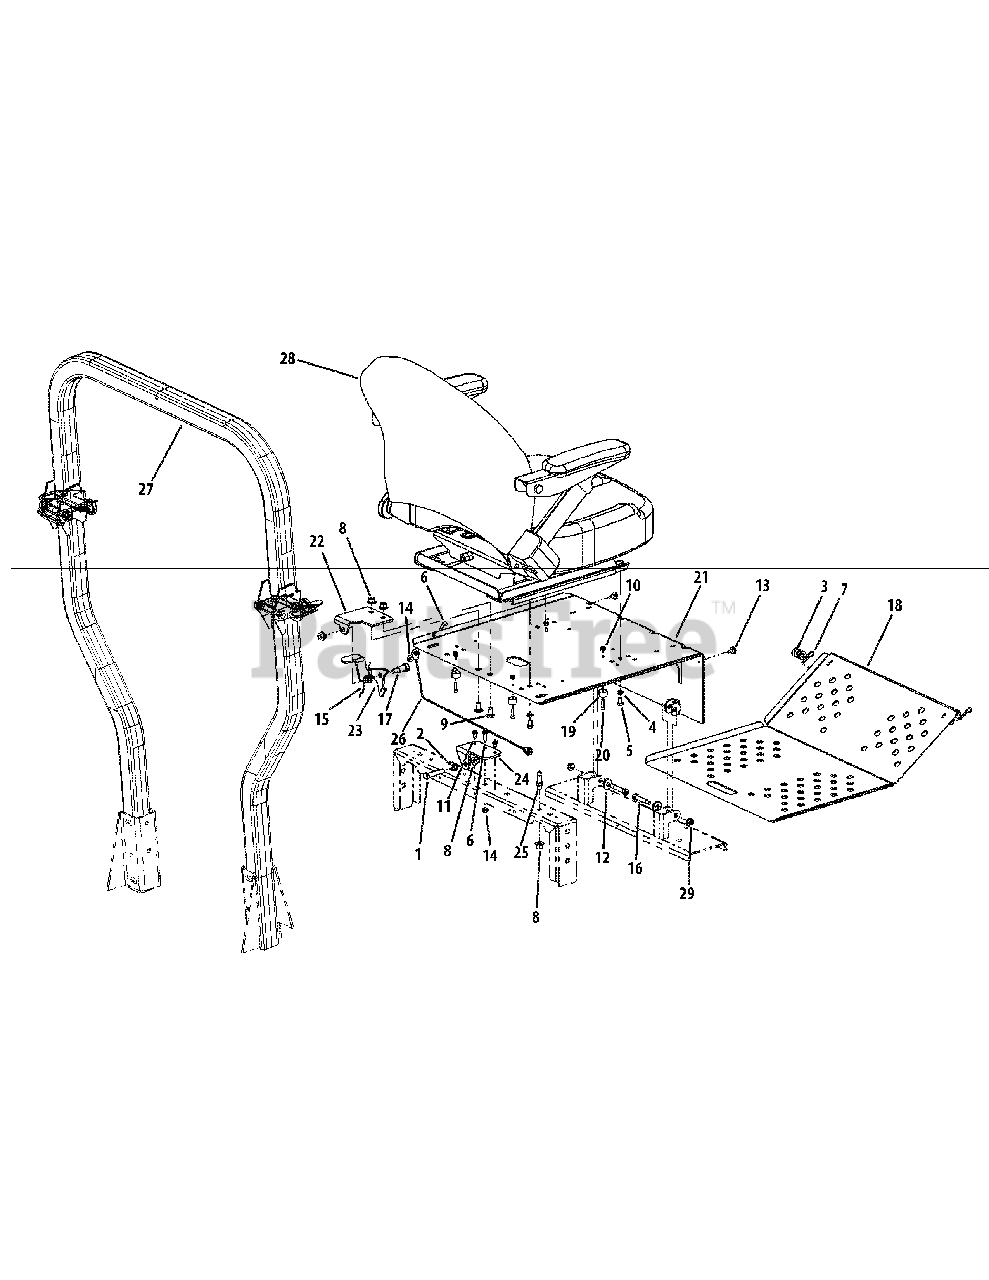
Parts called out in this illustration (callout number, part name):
1	Hex Cap Screw 3/8-16 x 2.00
2	Hex Nut, 3/8-16
4	Lock Washer, 5/16
5	Hex Cap Screw, 5/16-18 x 1/2
6	Screw, Hex, Cap, 1/4-20 x .75
7	Hair Pin, 3/8-1/2
8	Flange Lock, Hex Nut, 3/8-16
9	Carriage Bolt, 3/8-16 x .75 Long
10	Nut, #10-24, Nylon Lock
11	Screw, TT, 1/4-20, 0.5, Hex Washer
12	Flat Washer, .406 ID, 1.0 OD, .105
13	Rubber Bumper, .62 OD x .22 Thick
14	Lock Nut, 1/4-20
15	Deck Lift Spring, Left Hand
16	Shoulder Bolt, .375 x 1.50
17	Shoulder Bolt, 1/2 x 3/4, 3/8-16
18	Floor Panel Assembly
19	Rubber Stop with Washer
20	Standard Cap Screw, #10-24 x .75
21	Seat Plate Assembly
22	Seat Latch Bracket
23	Latch Lever Bracket
24	Latch Bracket
25	Adjustable Stud
26	Cable Support
27	Foldable Rops Assembly includes:
27	Pin, Lock
28	Seat w/ Seat Belt & Suspension
28	Armrest Kit
28	Seat Back Cover
28	Seat Bottom Cover
28	Seat Switch Assembly
29	Flange Lock Nut, 5/16-18
